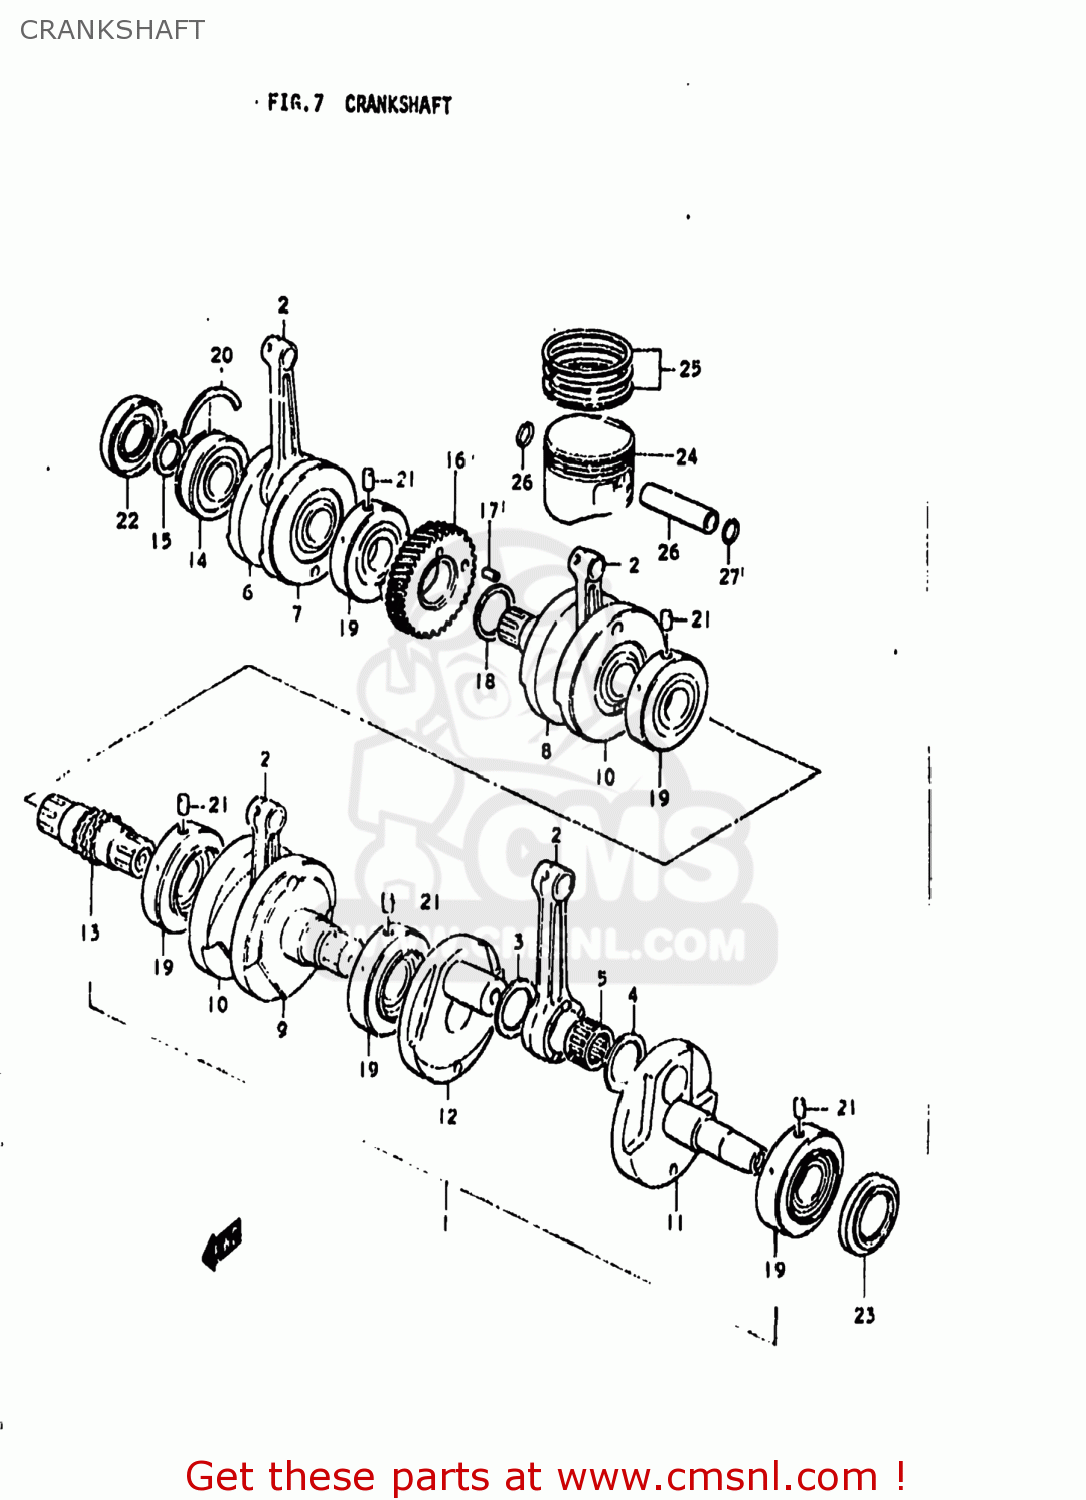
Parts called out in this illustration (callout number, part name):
1	CRANKSHAFT ASSEMBLY
2	CONNECTING ROD
3	WASHER (29X48X2)
4	WASHER (29X48X1)
5	BEARING(29X39X20)
6	CRANKSHAFT
7	WEB,CRANK,RIGHT
8	CRANKSHAFT
9	CRANKSHAFT, MIDDLE LH
10	WEB,CRANK,MIDDLE
11	CRANKSHAFT,LEFT
12	WEB,CRANK,LEFT
13	SHAFT,TIMING CHAIN DRIVE
14	BEARING(30X72X19)
15	CIRCLIP,30MM
16	GEAR,PRIMARY DRIVE
17	PIN
18	WASHER
19	BEARING
20	C RING
21	PIN
22	SEAL,OIL(30X72X11)
23	OIL SEAL
24	PISTON
25	RING SET,PISTON
26	PIN,PISTON
27	CIRCLIP
